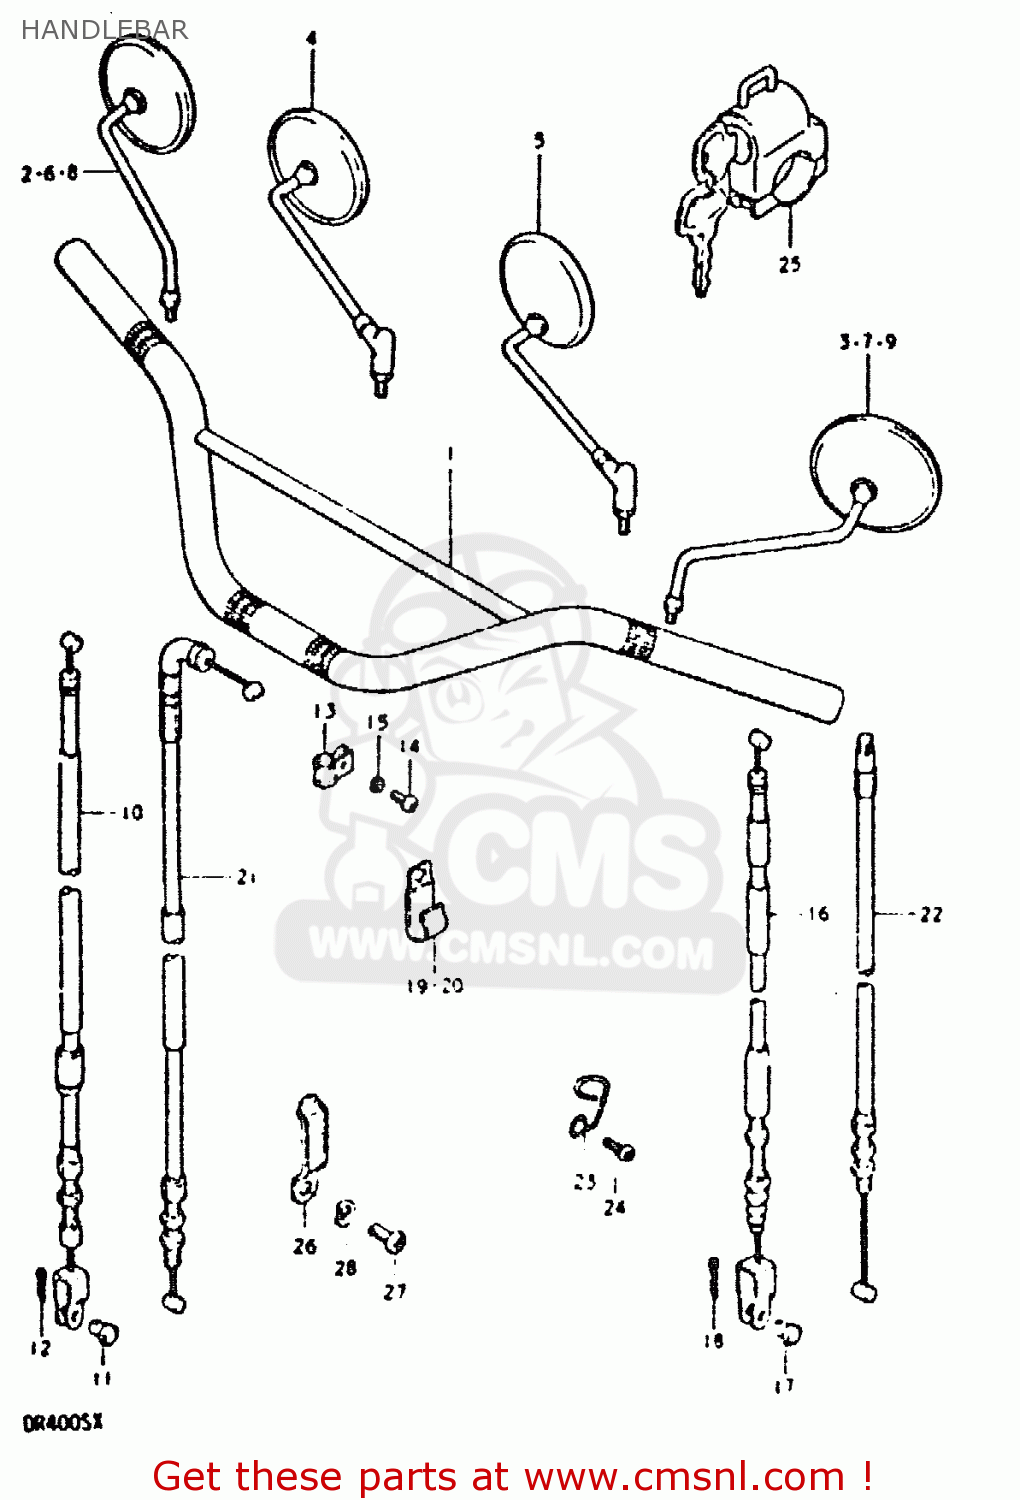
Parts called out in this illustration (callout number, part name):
1	HANDLEBAR (CHAMPAGE GOLD)
2	MIRROR ASSEMBLY,REAR VIEW
3	MIRROR ASSEMBLY,REAR VIEW
4	MIRROR ASSY,RH
10	CABLE ASSEMBLY,FRONT BRAKE
11	PIN(L:17.5)
12	PIN
13	GUIDE,CABLE
14	SCREW
15	LOCK WASHER
16	CABLE,CLUTCH
17	PIN(L:15)
18	PIN
19	CLAMP
20	CLAMP
21	CABLE ASSEMBLY,THROTTLE
22	CABLE, DECOMP
23	GUIDE
24	SCREW
